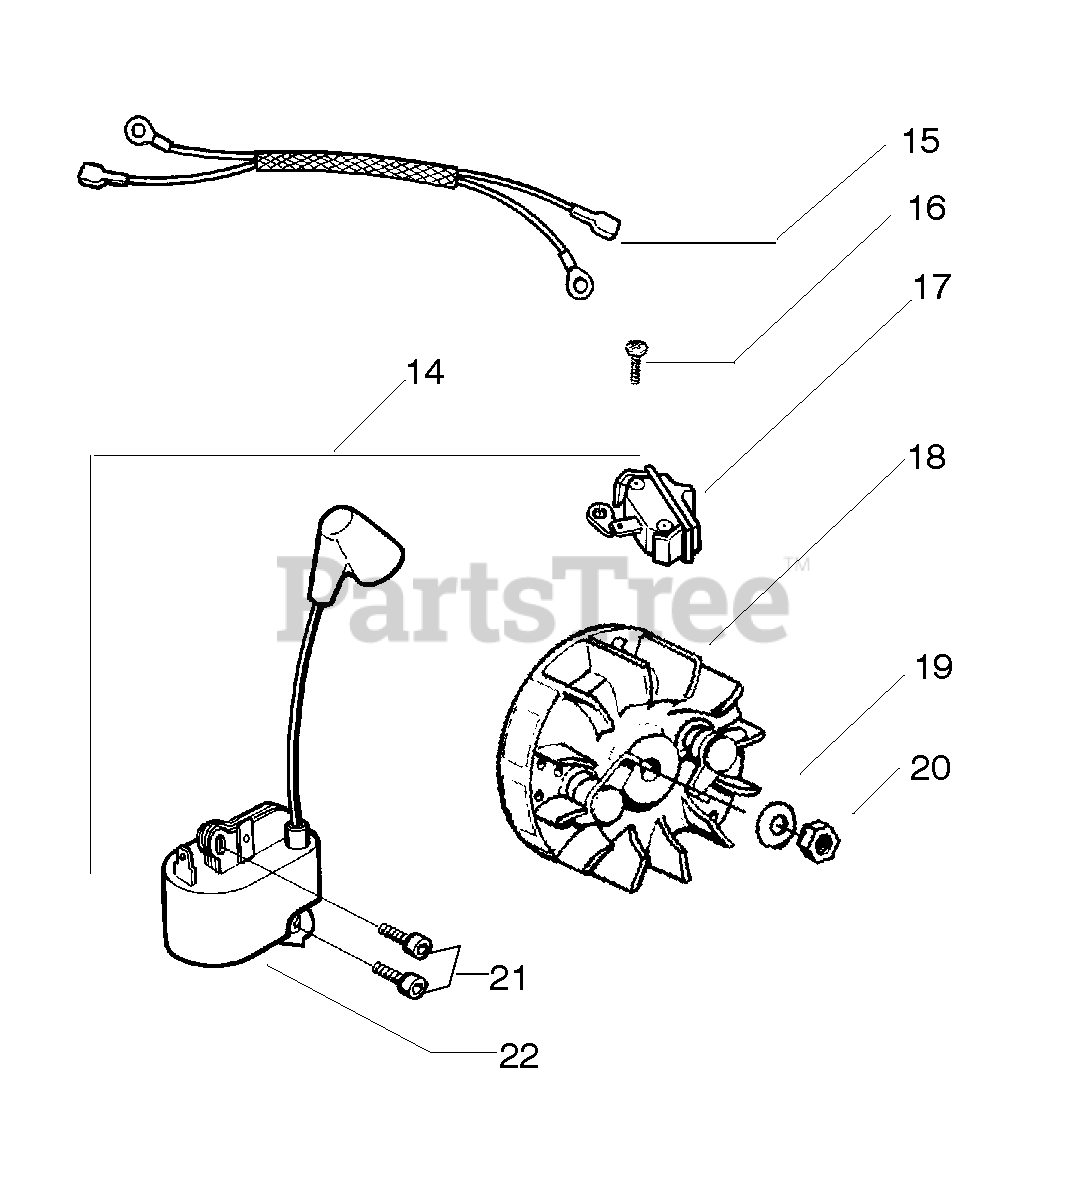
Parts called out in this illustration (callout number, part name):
14	Kit-EPS ignition
15	Assy-Leadwire
17	Switch-Ignition
18	Assy. -Flywheel
19	Washer-Flywheel
22	Module - Ignition
